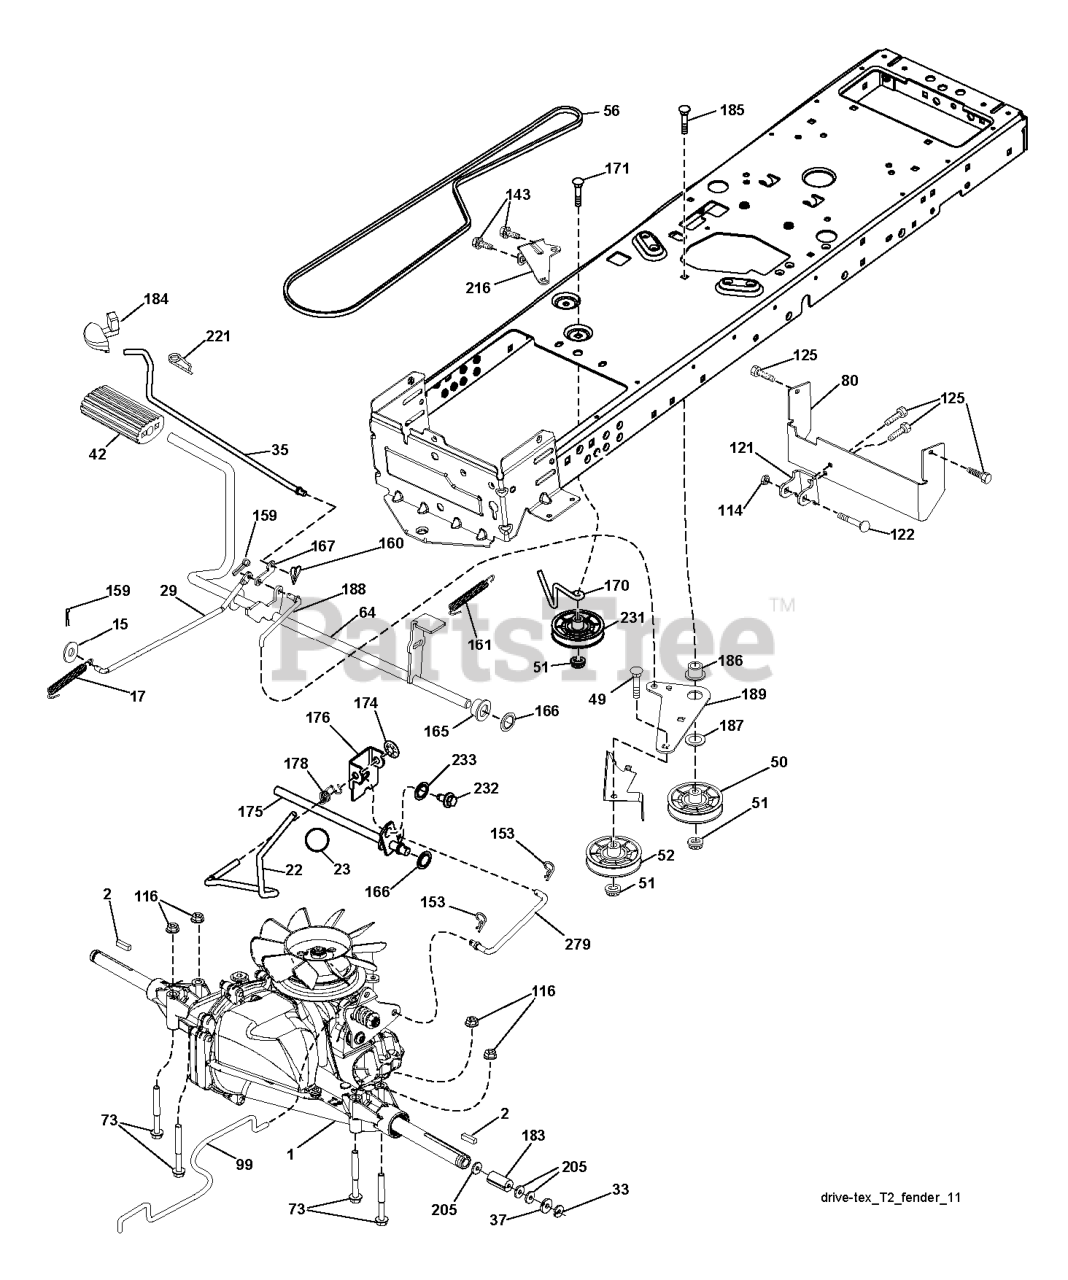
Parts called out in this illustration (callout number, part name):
2	SQUARE KEY
15	WASHER
17	SPRING.BRAKE.HG3000/3500
22	ROD.SHIFT.FENDER.TLT.2006
23	KNOB.DUCKHEAD.1/2
29	ROD.BRAKE.T2.TEX
35	ROD.CNTRL.PARK.PREDATOR.LT.TEX
42	PEDAL COVER T
50	IDLER.FLAT.910.OFFSET
51	NUT LOCK FLG 3/8-16 UNC
52	IDLER.V-GROOVE.910.OFFSET
64	SHAFT.ASM.PEDAL.BRAKE.
73	BOLT HEX 5/16-18 GR 5
80	RP.STRAP.TORQUE.FS.T2
99	ROD.ASM.BYPASS.SPRING.T2.FS
114	NUT.71038.31-18.HEX.NYLOCK
116	NUT LOCK HEX FLANGE 5/16-18
121	BRACKET STRAP TORQUE
122	BOLT.5/16-18X2.5
125	SCREW
143	Screw 5/16-18 x 1/2 Hex, Self Tapping 5/16-18 x 1/2
153	RETAINER M
159	COTTER PIN
160	RETAINER CLIP
161	SPRING, RETURN LT
162	ADAPTER.TRANSAXLE.T2.TLT.DRWBR
165	BUSHING.SHAFT.BRAKE.HAND
166	NUT.PUSH.625.2006
167	LATCH.BRAKE.SPRING
170	KEEPER.CENTER SPAN.1.688
174	NUT.PUSH.500.2006
175	SHAFT.ASM.SHFT.T2.TLT
176	ARM.CLEVIS.ROD.SHIFT
178	SPRING.SHIFT.GT2006
183	SPACER, AXLE PVST
184	HANDLE PARKING BRAKE
186	SPACER.RETAINER
187	WASHER 12/32X2X10GA
188	RP.LINK.CLUTCH.GROUND.DRIVE
189	BELLCRANK.GROUND.DRIVE.TEX.
190	KEEPER.BELLCRANK.DRIVE
216	BRACKET.PULLEY.IDLER.W/TEX
221	RETAINER.SPRING.CLIP.H
231	IDLER.V-GROOVE.1.688.OFFSET
232	BOLT FIN HEX 7/16-14 X 1
233	WASHER SERRATED
279	LINK SHIFT
